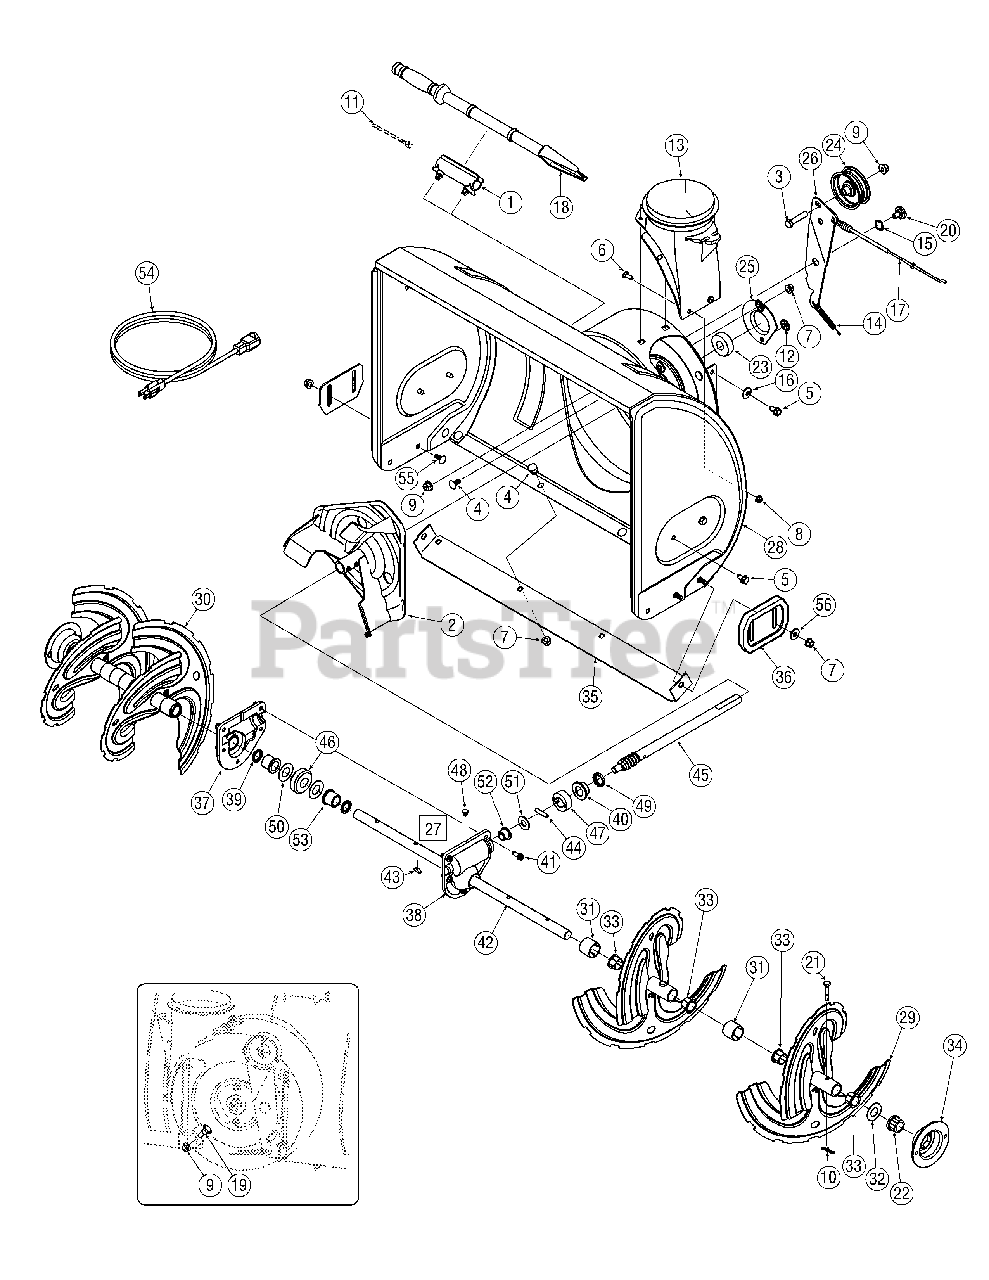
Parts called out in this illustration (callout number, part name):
1	Snow Removal Tool Mount
2	Impeller Assembly, 12" Dia.
3	Hex Screw, 3/8-16, 1.75, Gr5
4	Bolt, Carriage, 5/16-18, .750 Gr1
5	Screw, 5/16-18, 0.750
6	Screw, Carriage, 1/4-20, .750, Gr5
7	Nut, Flange Lock, 5/16-18, Nylon
8	Nut, Flange Lock, 1/4-20, Nylon
9	Nut, Flange Lock, 3/8-16, Nylon
10	Cotter Pin, Bow-tie
11	Cable, Tie, 3/16 x .05 x 7.4
12	Nut, Push-on, .25 Dia
13	Chute, Adapter 5" Dia
14	Spring, Extension, .38 OD x 4.59
15	Washer, Wave, .625 x .885 x .015
16	Washer, Bell, .340 x .872 x .060
17	Clutch Cable, Auger, 47.23"
18	Snow Removal Tool
19	Screw, Shoulder, .498 x .34, 3/8-16
20	Screw, Shoulder, .625 x .17, 3/8-16
21	Shear Pin, .25 x 1.50
22	Bearing, Hex Flange x .75 ID
23	Bearing, Ball, .75 ID x 1.85 OD
24	Flat Pulley, Idler, 2.75 OD
25	Housing, Bearing, 1.85 ID
26	Bracket, Auger Idler w/ Brake
27	Gearbox Assembly, Auger, 24"
28	Housing Assembly, Auger 24"
29	Spiral Assembly, LH
30	Spiral Assembly, RH
31	Spacer, 1.25 OD x .75 ID x 1.00
32	Washer, Flat, .76 x 1.49 x .06
33	Bushing, Flange, .80 ID x .91 OD
34	Housing, 1" Hex Bearing
35	Shave Plate, 2.25 x 23.66
36	Slide Shoe
36	Standard Polymer Reversible Shoe Kit
37	Housing, Auger, RH
38	Housing, Auger, LH
39	Seal, Oil, .750 x 1.00 x .125
40	Bearing, Flange, .75 x 1.0 x .59
41	Screw, Self-tapping, 1/4-20, 0.750
42	Axle, Auger, 24"
43	Key, Hi-pro 3/16 x 5/8
44	Pin, Dowel, .25 OD x 1.2
45	Shaft, Worm .75 OD
46	Gear, Worm 20T
47	Collar, Thrust
48	Plug, 1/4 x .437
49	Seal, Oil, .75 x 1 x .131
50	Washer, Flat, .760 ID x 1.5 OD
51	Washer, Flat, .51 x 1.12
52	Bearing, Flange, .75 x 1.0 x .925
53	Bearing, Flange, .75 x 1.00 x .975
54	Extension Cord, 110V
55	Screw, Carriage, 5/16-18 x 1.00
56	Washer, Flat, .349 x .879 x .063
